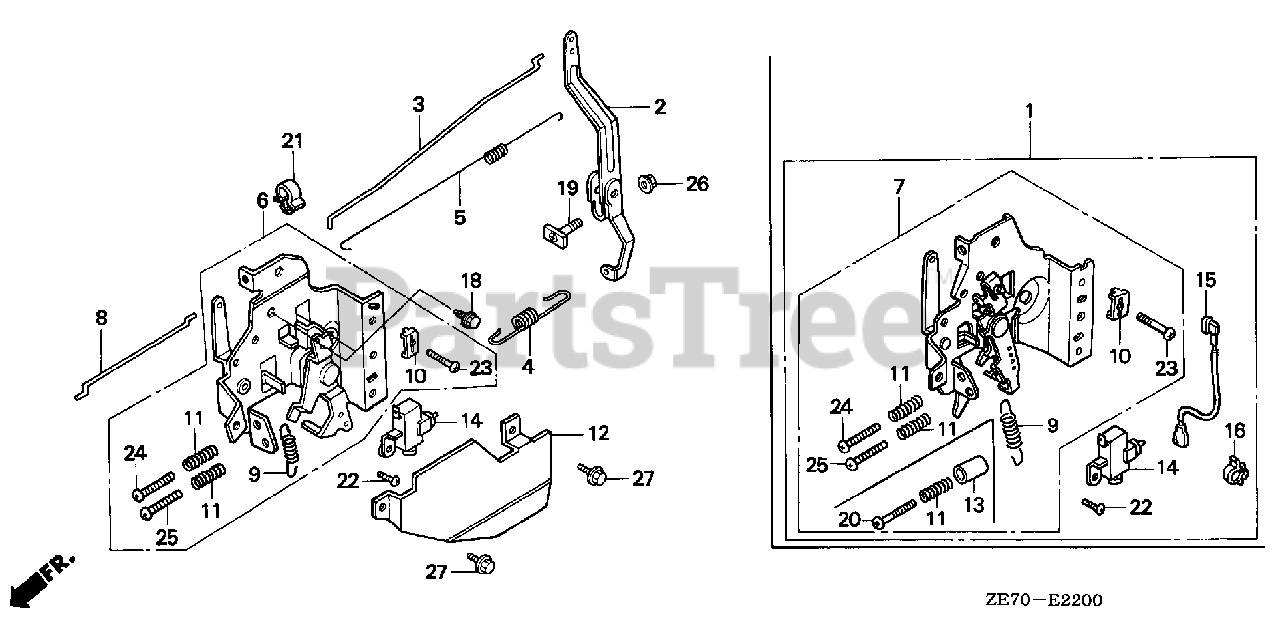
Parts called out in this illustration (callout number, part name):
2	ARM, GOVERNOR
3	ROD, GOVERNOR
4	SPRING, GOVERNOR
5	SPRING, THROTTLE RETURN
6	CONTROL ASSY.
8	ROD, CHOKE
9	SPRING, LEVER
10	HOLDER, CABLE
11	SPRING, CONTROL ADJUSTING
12	PROTECTOR, CONTROL
14	SWITCH ASSY., ENGINE STOP
18	BOLT, FLANGE (6X12) (CT200)
19	BOLT, GOVERNOR ARM
21	CLIP, WIRE HARNESS
22	SCREW, PAN (4X8)
23	SCREW, PAN (5X16)
24	SCREW, PAN (5X20)
25	SCREW, PAN (5X28)
26	NUT, FLANGE (6MM)
27	BOLT, FLANGE (6X10)
